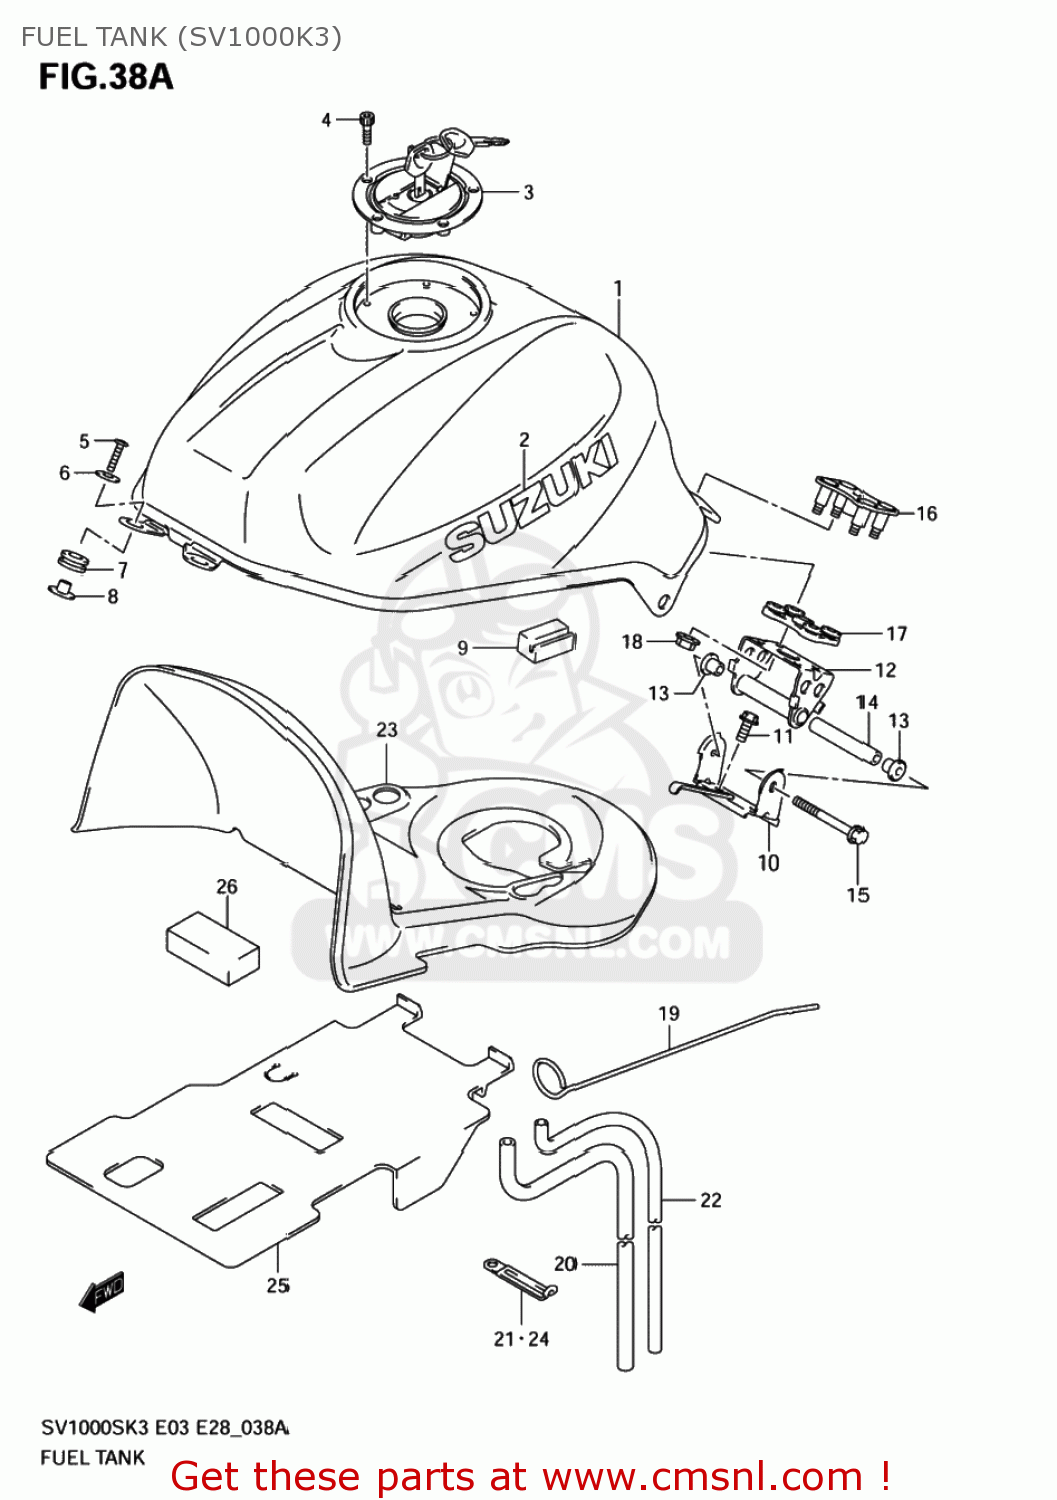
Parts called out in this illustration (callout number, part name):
1	TANK ASSY,FUEL(BLUE)
2	EMBLEM
3	CAP SET,FUEL TANK
4	BOLT(5X20)
5	SCREW(6X25)
6	WASHER(6.5X22X1.6)
7	CUSHION,FUEL TANK FR
8	SPACER,FUEL TANK FR
9	CUSHION,FUEL TANK SIDE
10	BRACKET,FUEL T
11	BOLT
12	BRACKET,FUEL TANK NO.1
13	CUSHION,TANK RR BRACKET
14	SPACER,FUEL TANK RR
15	BOLT(6X100)
16	BRACKET,FUEL TANK RR UP
17	CUSHION,FUEL TANK RR
18	NUT
19	STAY,FUEL TANK
20	HOSE,WATER DRAIN
21	CLAMP(L:80)
22	HOSE,FUEL TANK
23	SHIELD,FUEL TANK HEAT
24	CLAMP(L:80)
25	SHEET,HEAT SHIELD RUBBER
26	CUSHION,FUEL TANK
